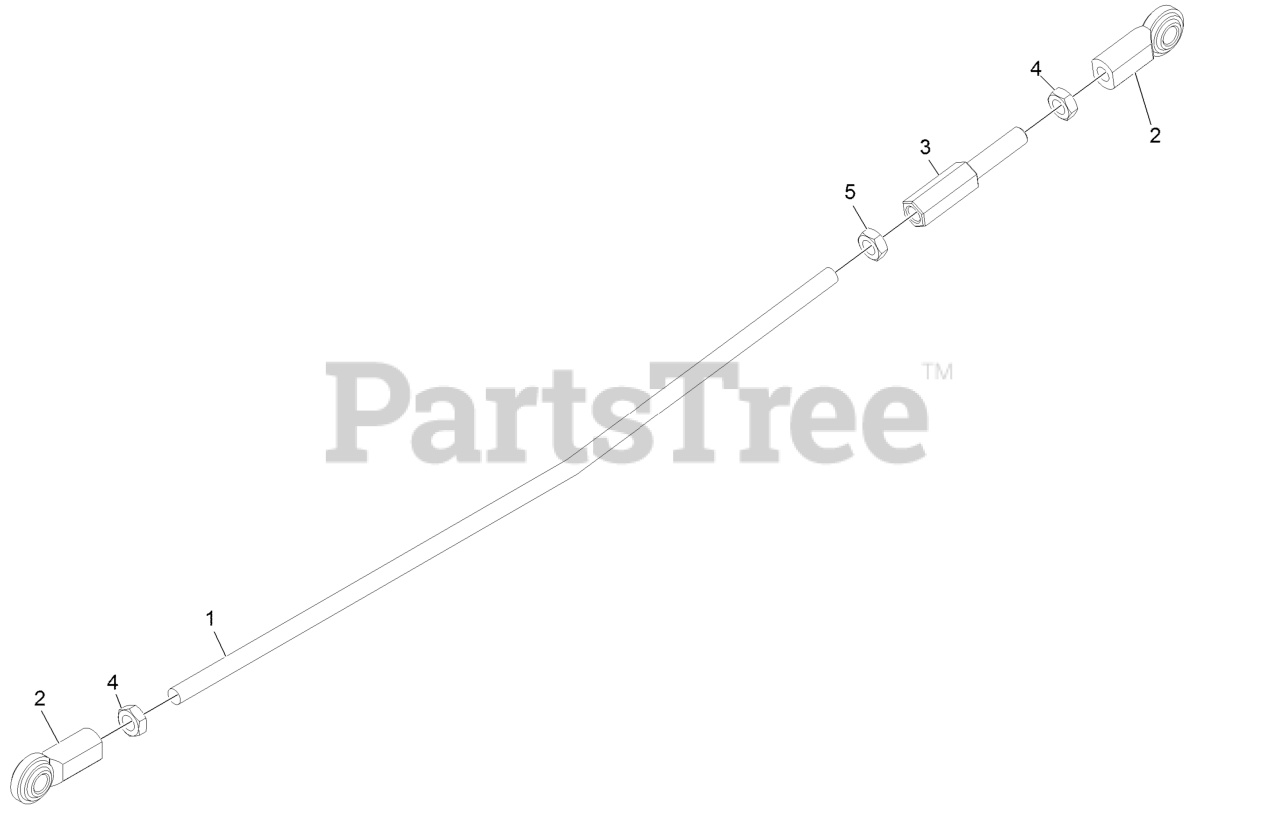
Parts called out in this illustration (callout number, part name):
1	LINK-LOWER, MOTION CONTRO
2	JOINT-BALL, END
3	ROD-ADJUSTMENT
4	NUT-HJ
5	NUT-HEX JAM, LH
